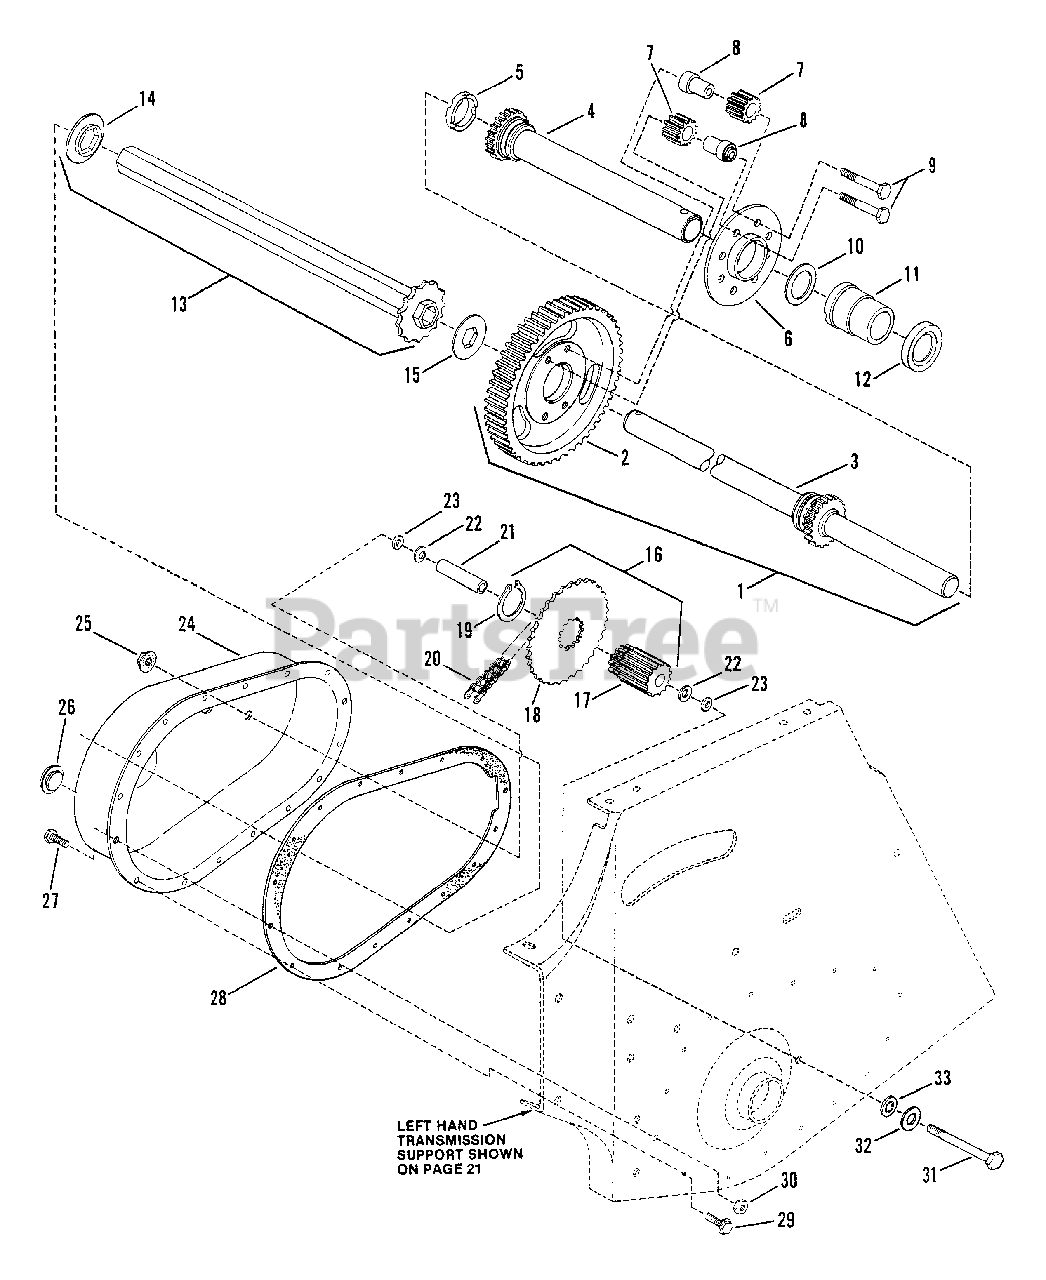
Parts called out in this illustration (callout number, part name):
1	ASSEMBLY, Differential
2	GEAR, 63 Teeth, 10 Pitch
3	AXLE, Long
4	AXLE, Short
5	SPACER, Differential (1.25" ID x .425 Wide)
6	PLATE, Differential
7	PINION GEARS, Differential
8	SPACER, Pinion
9	BOLT, 5/16-24x1-5/8" Hex, Special Lock Cap
10	WASHER, Thrust
11	BEARING, Axle, L.H. Transmission Support (Listed with L.H. Fender Assm'y. on Page 21)
12	SEAL, Oil
13	ASSEMBLY, Drive Hex Tube
14	WASHER,Hex Insert
15	WASHER, Thrust
16	ASSEMBLY, Gear & Sprocket
17	GEAR, 11 Teeth, 10 Pitch
18	SPROCKET
19	RING, Retaining
20	CHAIN, 46 Pitch (#35)
21	SPACER
22	WASHER, Belleville
23	O-RING, 5/16"
24	CASE, Transmission
25	NUT, 5/16-24 Hex Flange Lock
26	PLUG, Oil Fill & Check
27	SCREW, 1/4-20x5/8" Hex Head Cap
28	GASKET, Transmission Case
29	SCREW, 1/4-20x5/8" Self-Tapping
30	NUT, 1/4-20 Hex Lock
31	BOLT, Idler, 5/16-24x2-5/8"
32	WASHER, Flat
33	WASHER, 5/16" Internal Tooth Lock
